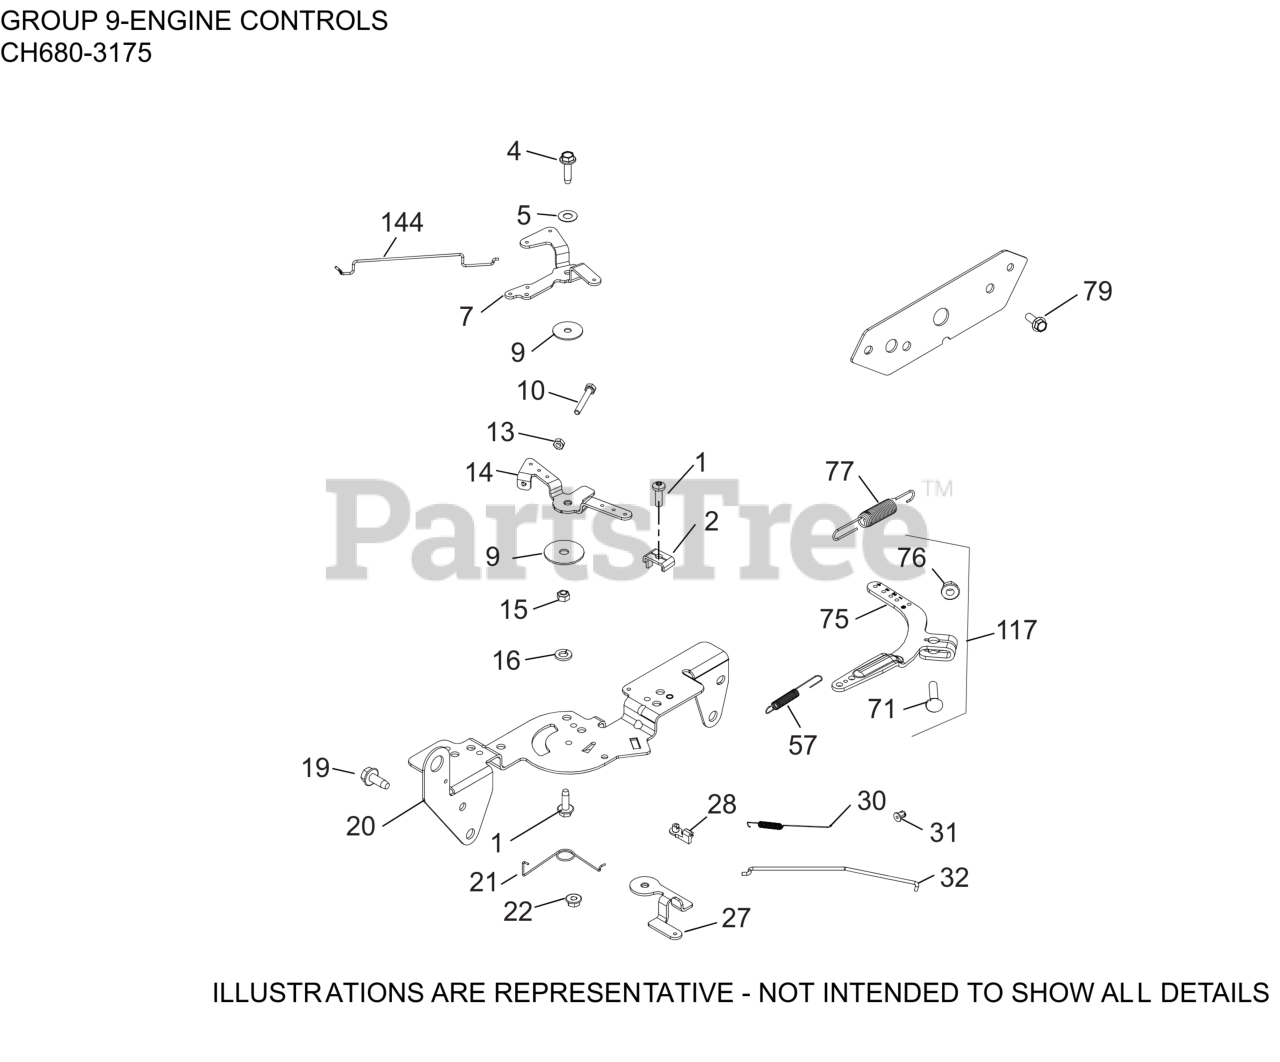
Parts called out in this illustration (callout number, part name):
1	SCREW, THREAD FORMING
2	CLAMP, CABLE CABLE
4	SCREW, THD FRM-USE 25 086 473-S
5	WASHER, SPRING 1/4"
7	LEVER, CHOKE
9	WASHER, FLAT 5.5 MM
10	SCREW, CAP M4X.7X30
13	NUT, M4X0.7
14	LEVER, THROTTLE CONTROL
15	NUT, FLG M5X.8
16	WASHER, SPRING LOCK 1/4"
19	SCREW, THREAD FORMING
20	BRACKET, CONTROL
21	SPRING, CHOKE RETURN
22	NUT, LOCK M5X.8
27	LEVER, THROTTLE ACTUATOR
28	BUSHING, THROTTLE LINKAGE
30	SPRING, LINKAGE
31	BUSHING, LINKAGE RETAINING
32	LINKAGE, THROTTLE
57	SPRING, THROTTLE LIMITER
71	BOLT, RD HD SQ NECK M6X1.0X25
75	LEVER, GOVERNOR - (#2409069S)
76	NUT, FLG M6X1.0
77	SPRING, GOVERNOR (PURPLE)
79	SCREW, HI-LOW
117	LEVER, GOVERNOR ASSEMBLY
144	LINKAGE, CHOKE
